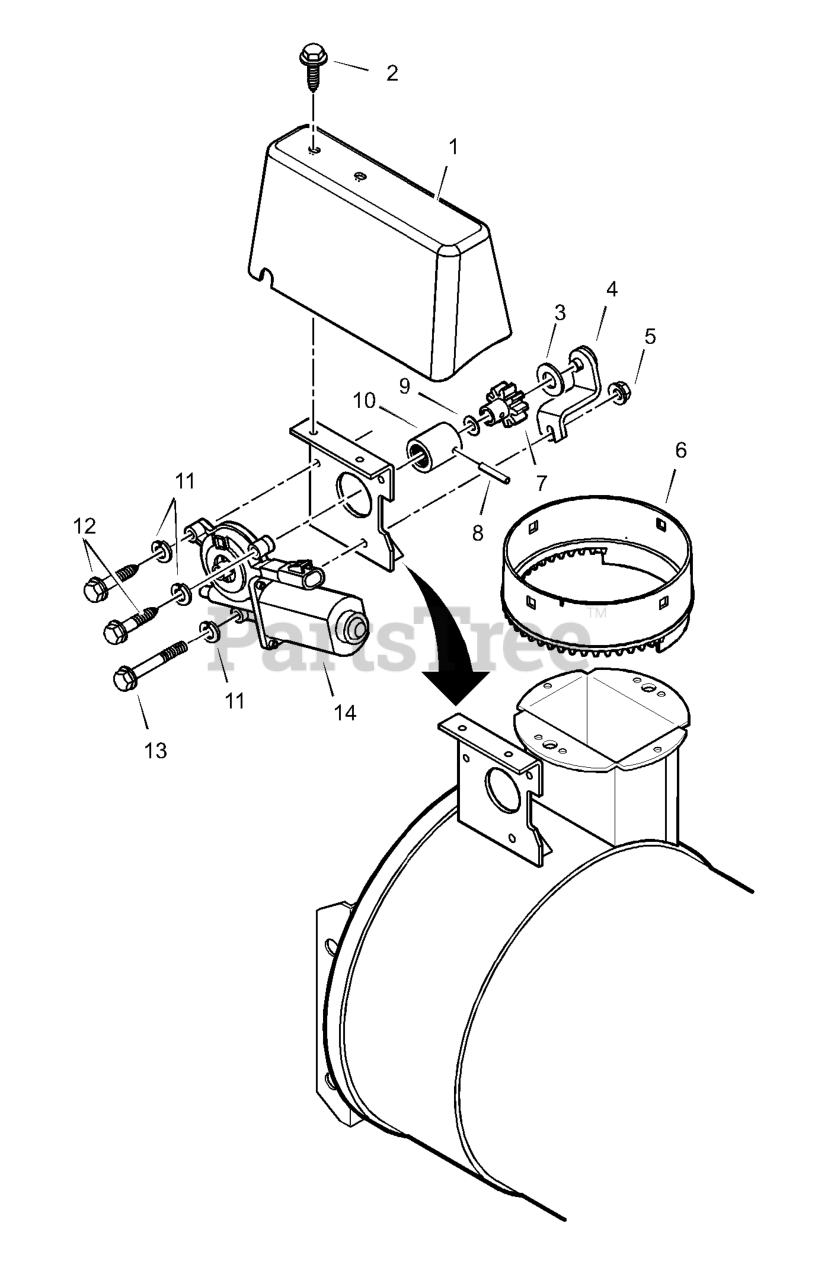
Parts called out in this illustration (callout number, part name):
1	COVER, ELECTRIC MOTOR
3	WASHER
4	ASSEMBLY, BRACE CHUTE GEAR
6	RING, ELECTRIC OUTER GEAR
8	PIN, SPRING
9	RING, RETAINER
10	ADAPTER, CHUTE GEAR
11	WASHER, SPLIT
13	BOLT, HEX
14	MOTOR, ELECTRIC CHUTE
